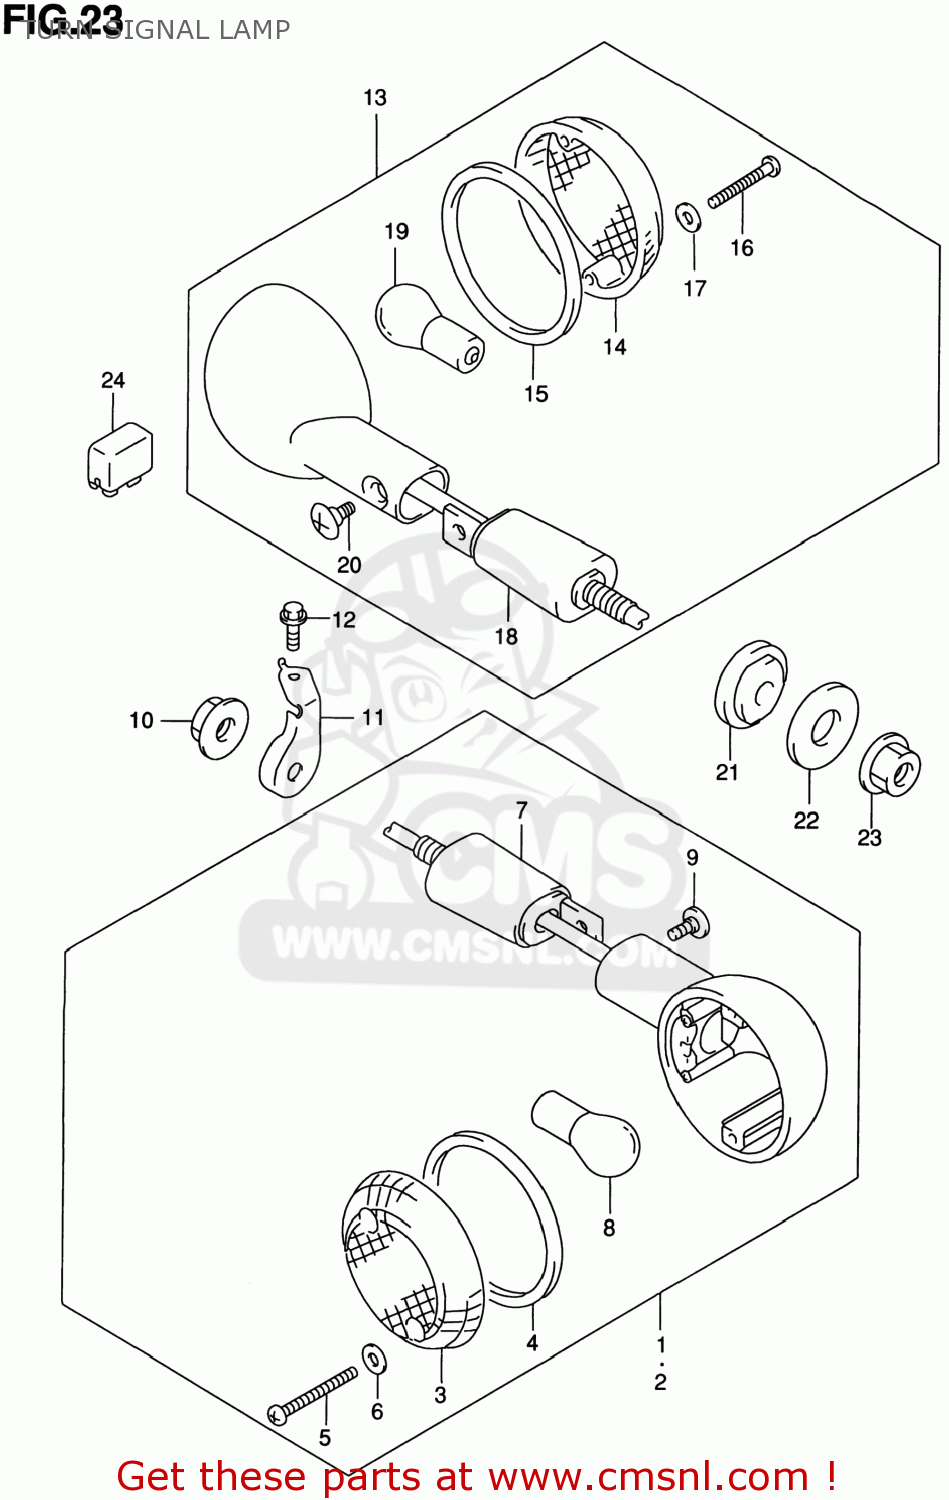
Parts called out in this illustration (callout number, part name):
1	LAMP ASSY,FR TURN SIGNAL,R
2	LAMP ASSEMBLY,FRONT TURN SIGNAL
3	LENS
4	GASKET (NAS)
5	SCREW
6	GASKET (NAS)
7	STAY,TURNSIGNAL FR
8	BULB(12V21/5W,BF141-49642A)
9	SCREW
10	NUT
11	BRACKET,FR TURNSIGNAL,R
12	BOLT
13	LAMP ASSY,RR TURNSIGNAL
14	LENS
15	GASKET (NAS)
16	SCREW
17	GASKET (NAS)
18	STAY,TURNSIGNAL RR
19	BULB(12V21W)
20	SCREW
21	SPACER,RR TURNSIGNAL
22	WASHER(10.5X30X2.3)
23	NUT
24	RELAY ASSY,TURNSIGNAL LAMP
